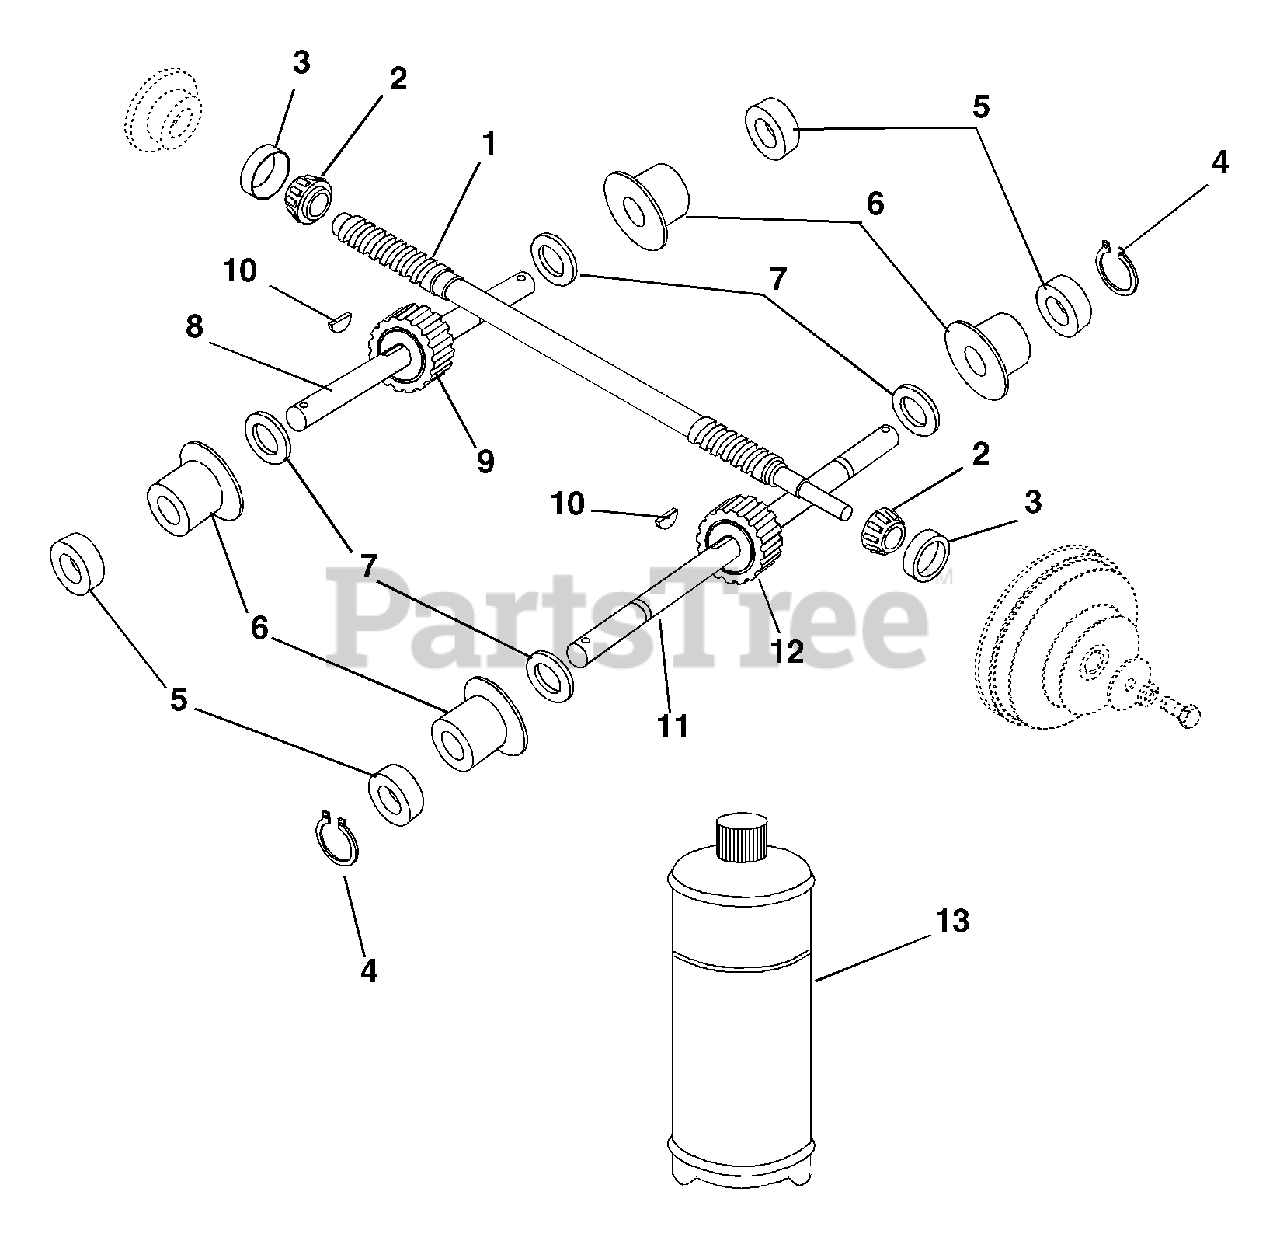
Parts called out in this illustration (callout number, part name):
1	WORM SHAFT
2	BRG-CONE .750X.61
3	BRG-CUP 1.781X.475
4	RG-RTNG .822X1.500X.050 TYP E
5	SEAL 1.000X1.312X.150
6	BSHG-FLG 1.000X1.125X1.875
7	WSHR-HDND-THRUST 1.00X1.55X.03
8	TINE SHAFT
9	WORM GEAR
10	KEY-WDRF .25X.875X.375 SAE A
11	WHEEL SHAFT
12	WORM GEAR 61
13	ARIENS 16 OZ.BOTTLE OF L2 LUBE
